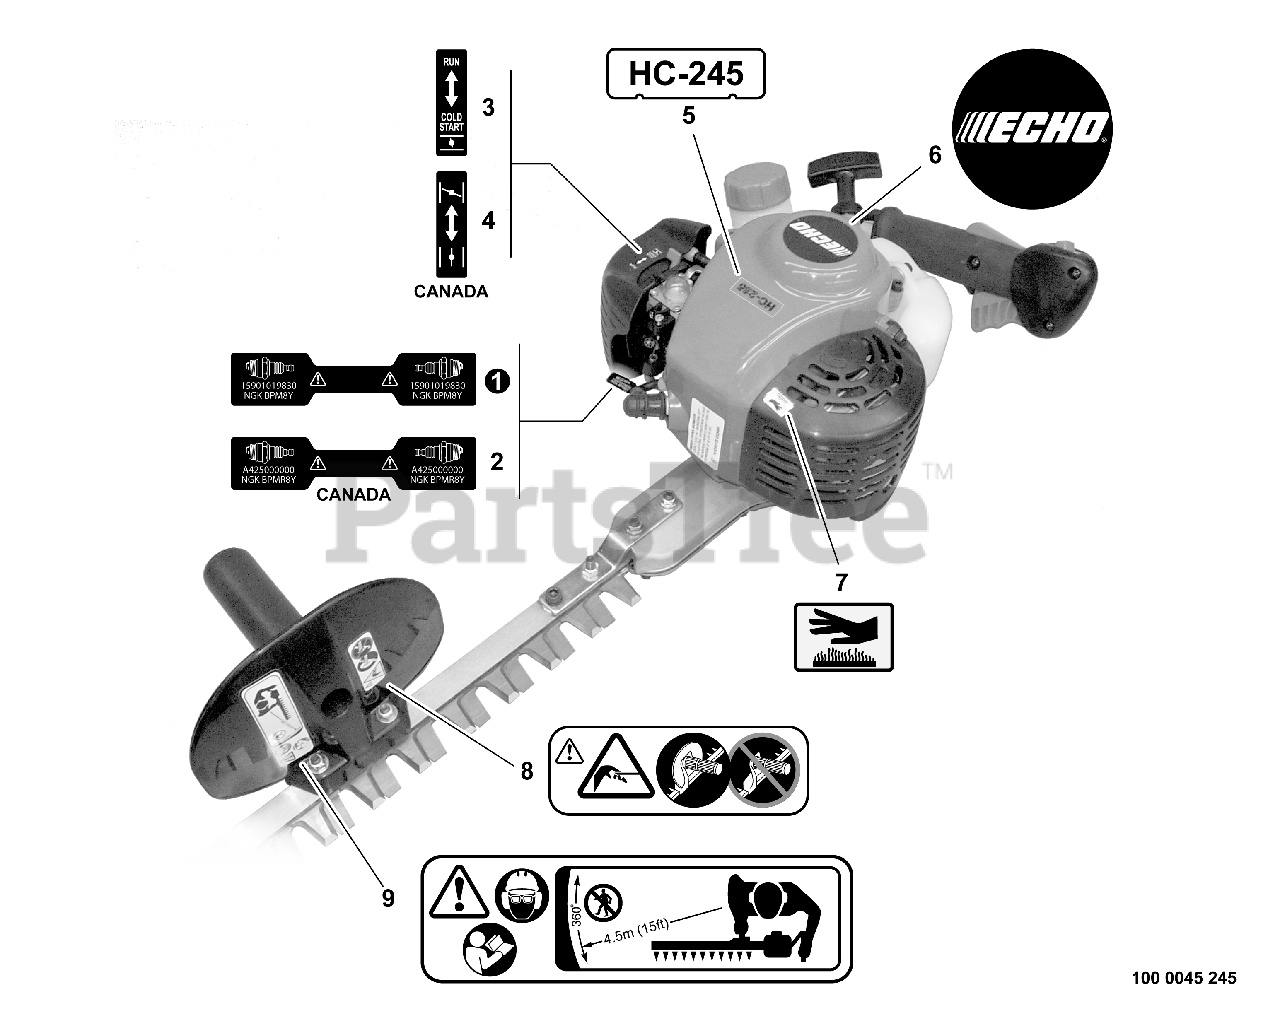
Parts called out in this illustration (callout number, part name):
1	LABEL - SPARK PLUG -- BPM-8Y
2	LABEL - SPARK PLUG -- BPMR-8Y
3	LABEL - CHOKE
4	LABEL - CHOKE
5	LABEL - MODEL HC-245
6	LABEL - ECHO
7	LABEL - HOT SURFACE
8	LABEL - CAUTION
9	LABEL - CAUTION
